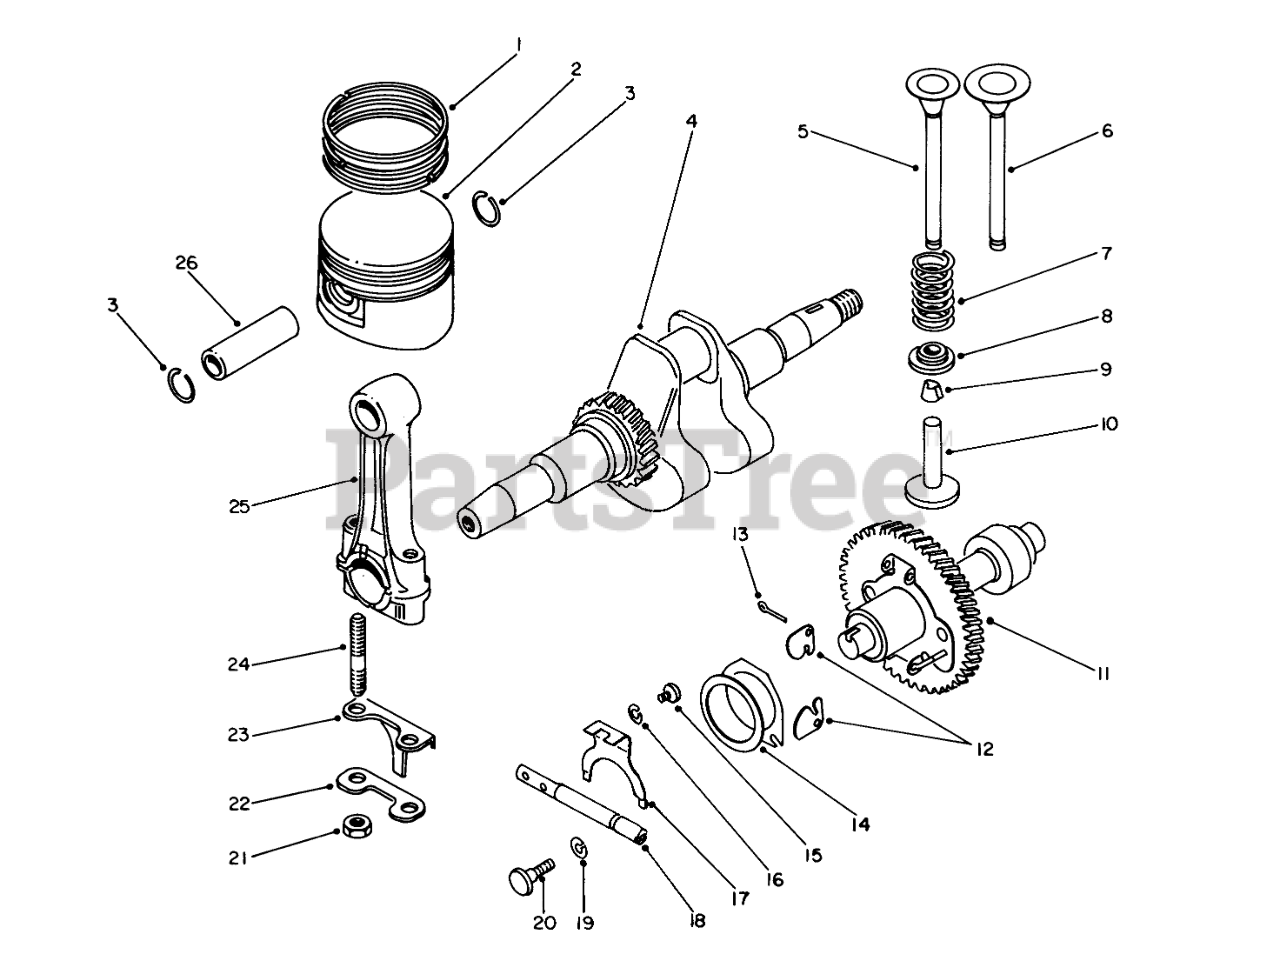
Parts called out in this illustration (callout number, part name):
1	Ring Set-Piston Std.
2	Piston Std
3	CIRCLIP
4	Crankshaft
5	EXHAUST VALVE
6	Valve-Intake
7	Spring-Valve
8	Retainer
9	Cotter
10	Tappet (L:40.26)
11	Cam Shaft
13	Cotter Pin
14	Spacer
15	SCREW
16	Lockwasher
17	Plate-Shift
18	Shaft-Throttle Return
19	Gasket
20	Screw
22	LOCK PLATE
23	Plate-Splash
24	Stud Bolt
25	Rod-Connecting (Incl. Ref. #21-24)
26	PISTON PIN
